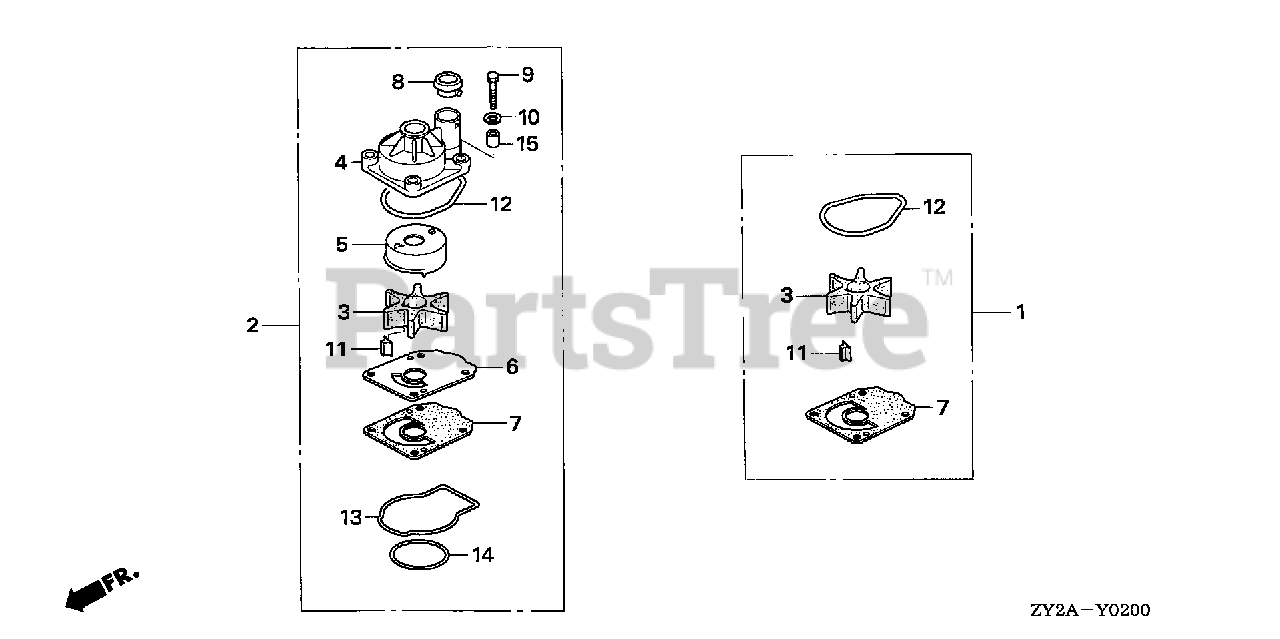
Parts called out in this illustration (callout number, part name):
1	PUMP KIT, IMPELLER
2	PUMP KIT, IMPELLER
3	IMPELLER, PUMP
4	HOUSING, IMPELLER
5	LINER, PUMP
6	COVER, IMPELLER
7	GASKET B, IMPELLER
8	RING, WATER TUBE SEAL
9	BOLT, HEX. (8X60)
10	WASHER (8MM)
11	KEY, WOODRUFF
12	O-RING, WATER PUMP
13	O-RING, WATER PUMP HOUSING
14	O-RING (69.1X2.4)
15	COLLAR, DISTANCE
